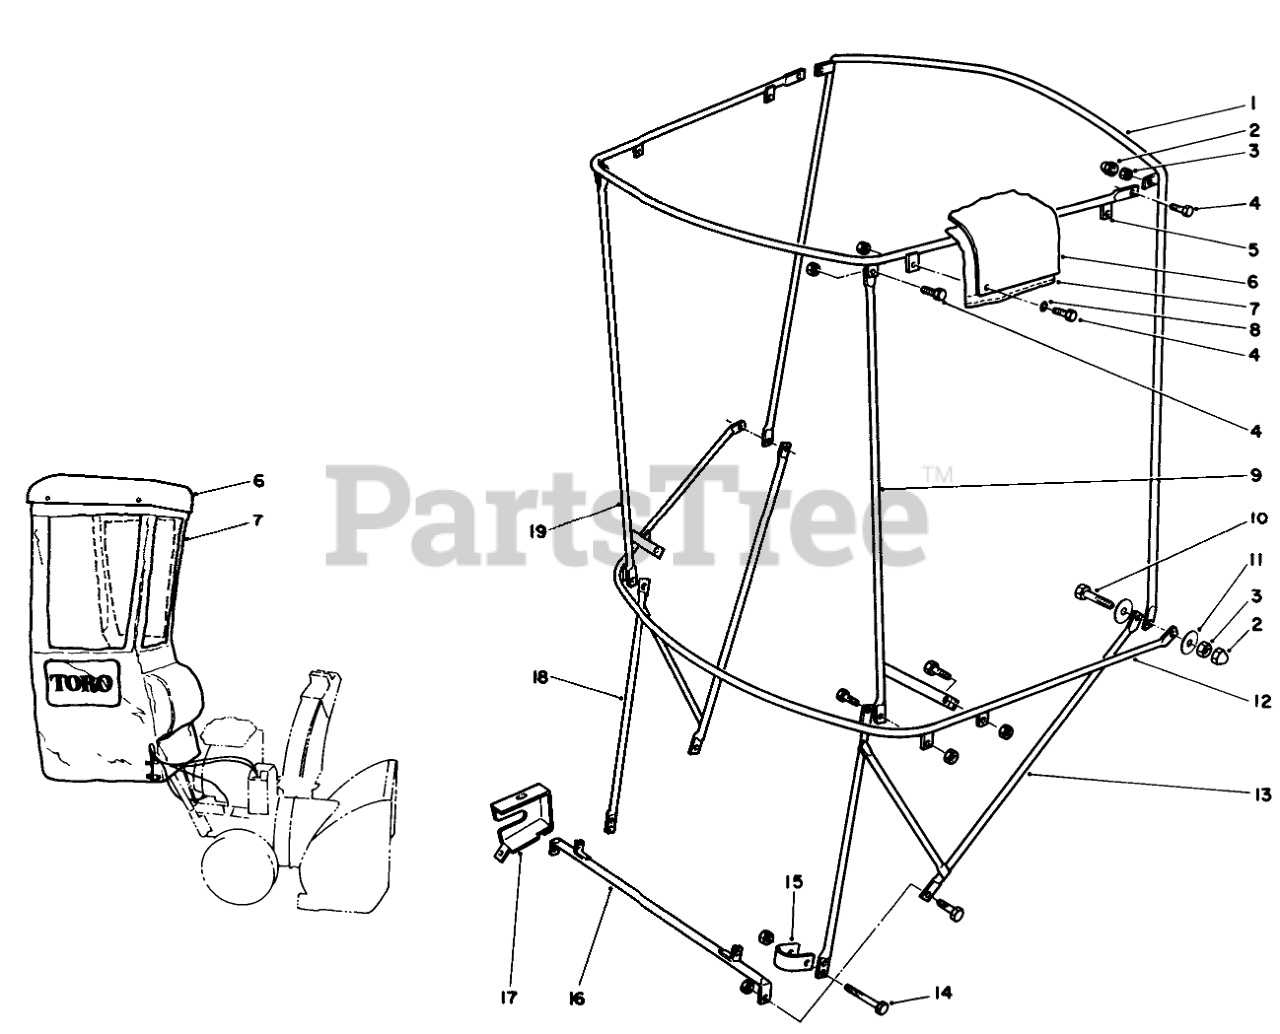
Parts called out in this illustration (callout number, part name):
1	VERTICAL BOW
2	CAPLUG
3	NUT-HEX, SIDE DEFORM
4	SCREW-HH
5	FRAME - TOP
6	Top-Plastic
7	Cover-Vinyl
8	WASHER-FLAT
9	CORNER POST - LH
10	SCREW-HH
11	WASHER-FLAT
12	HORIZONTAL BOW
13	Bracket-LH
14	SCREW-HH
15	CLAMP
16	Bracket-Base
17	COVER-LOCK, LEVER
18	BRACKET-RH
19	CORNER POST - RH
